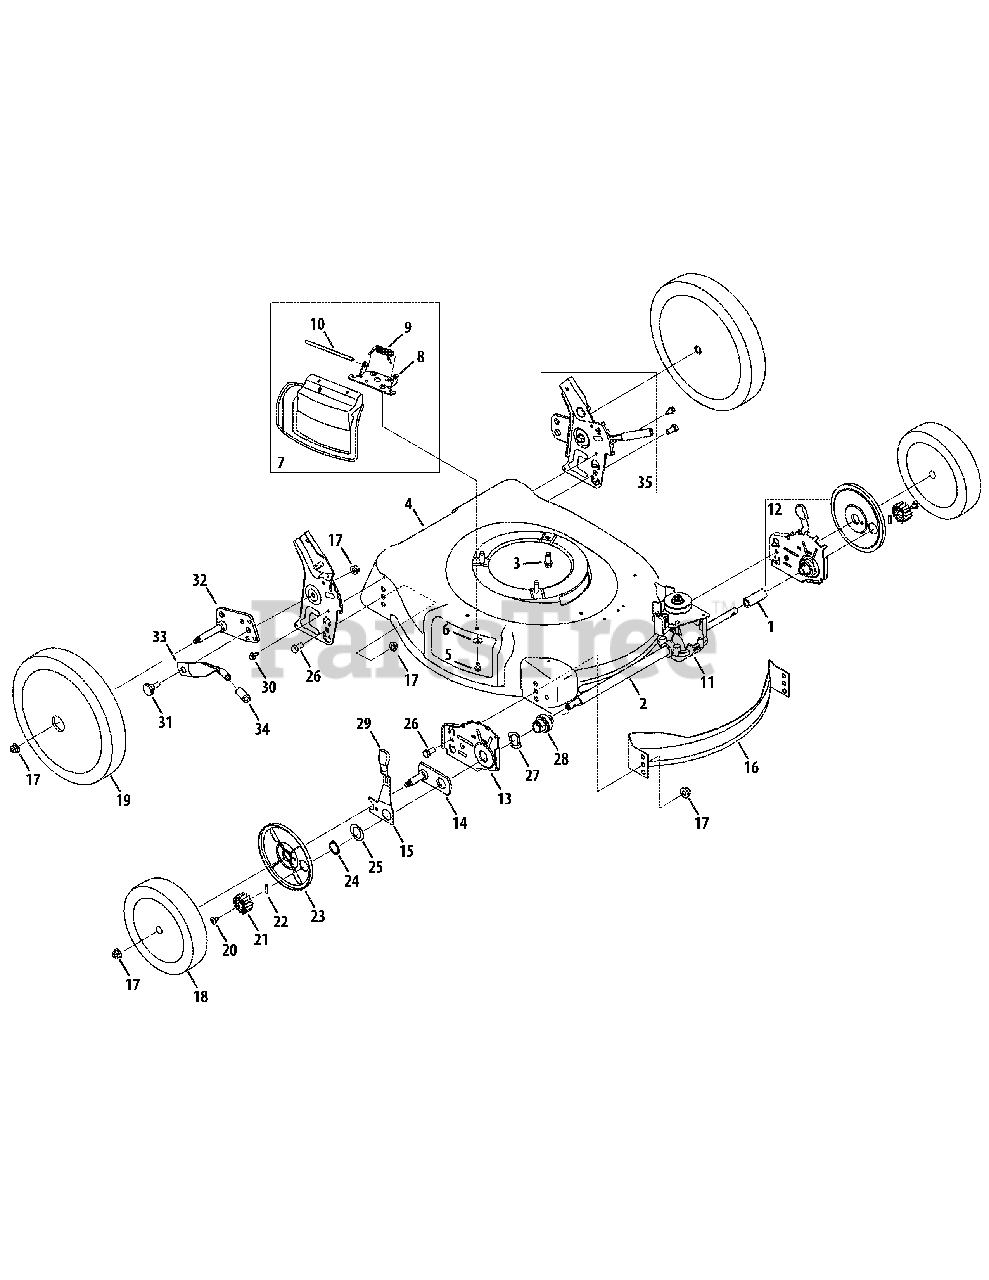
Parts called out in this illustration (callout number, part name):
1	Sleeve, Spacer, 1.8'' Lg.
2	Sleeve, Spacer, 9.10'' Lg.
3	Self-Tapping Sems Screw
6	Bell Washer
7	Hinged Mulch Plug Assembly
8	Chute Deflector Adapter
9	Torsion Spring
10	Hinge Pin
11	Transmission Assembly
12	Height Adj. Assembly - LH
12	Height Adj. Assembly - RH
13	Front Height Adj. Plate - RH
13	Front Height Adj. Plate - LH
14	Pivot Plate Assembly
15	Front Lever - RH
15	Front Lever - LH
16	Front Baffle
17	Flange Lock Nut, 3/8-16
18	Front Wheel, 8x 2.125
19	Rear Wheel, 12 x 2.125
20	Screw, 1/4-20 x .390
21	Gear 14T RH FWD RH
21	Gear 14T LH FWD LH
22	Dowel Pin
23	Wheel Dust Cap
24	Snap Ring
25	Flat Washer
26	Hex Screw, 3/8-16 x .75
27	Wave Washer
28	Bearing Assembly
29	Adjustment Knob
30	TT Screw w/Washer, 1/4-20 x .625
31	Shoulder Screw, .500 Dia x .385
32	Pivot Arm Assembly - RH
32	Pivot Arm Assembly - LH
33	Rear Spring Lever
34	Foam Grip
35	Handle Bracket Assembly - LH
35	Handle Bracket Assembly - RH
